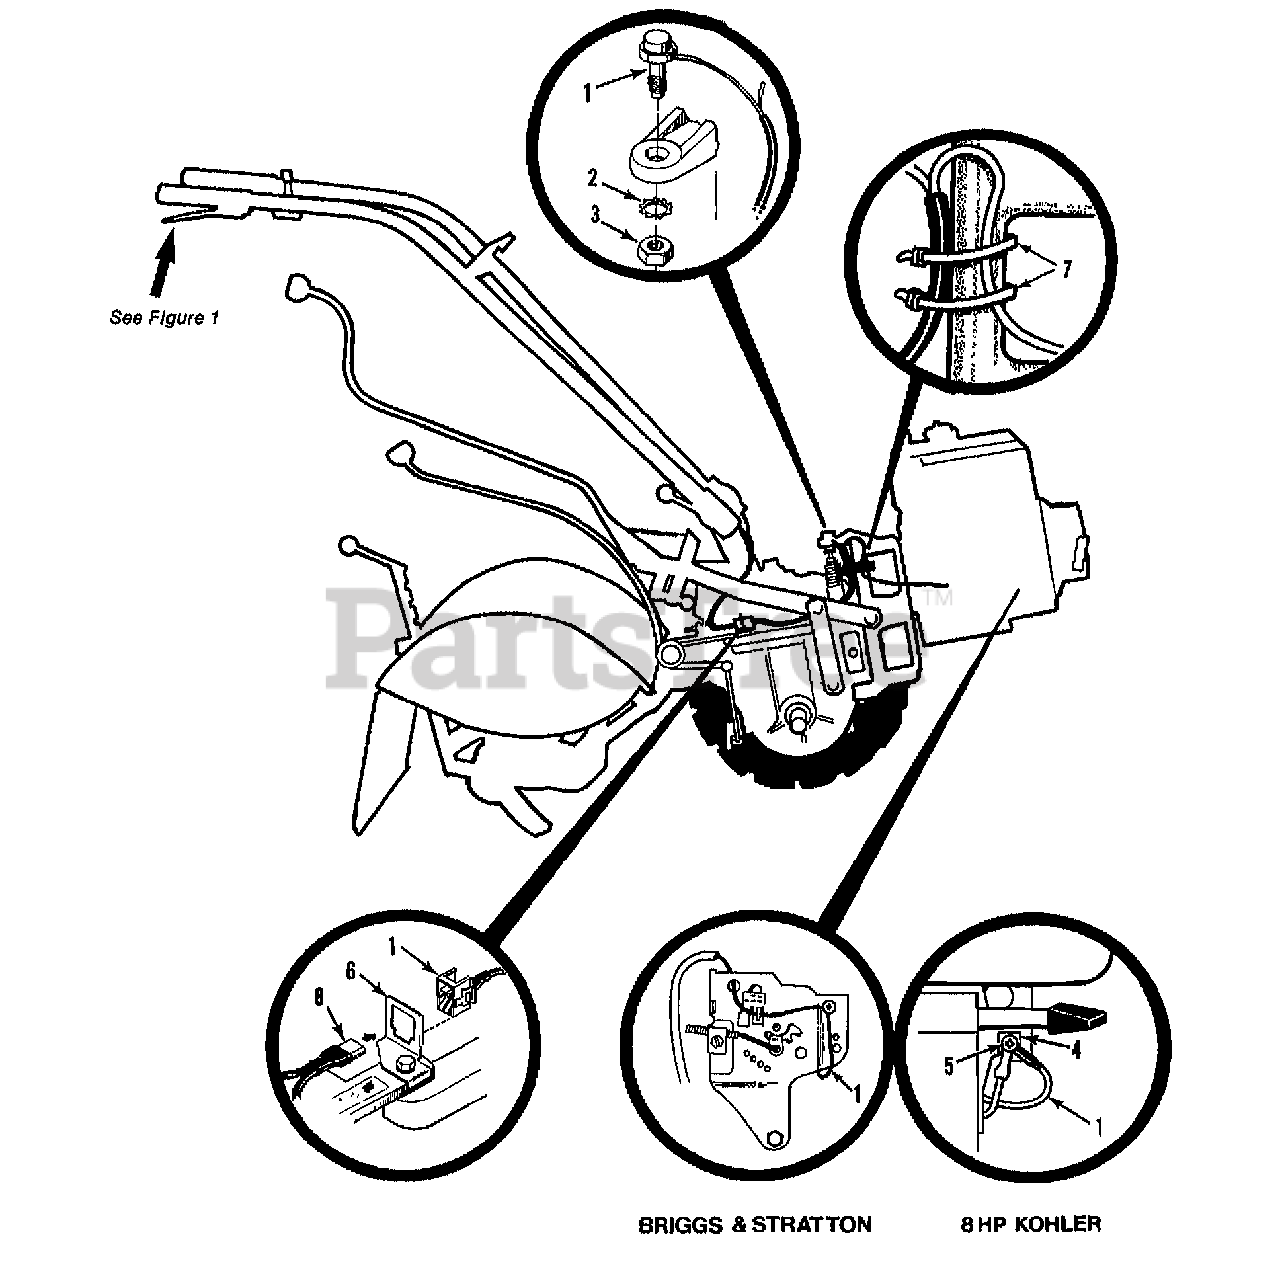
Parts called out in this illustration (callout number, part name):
1	HARNESS-WIRE ENG OPC
2	WASHER-LK .438 EXT TOOTH
3	NUT-HEX/JAM 7/16-20
4	GROMMET-7 T/L & 8 KOH OPC
5	SCR #8-18 SELF TAP
6	CLIP-CONNECTOR
7	TIE-RED
8	HARNESS-WIRE OPC HORSE
